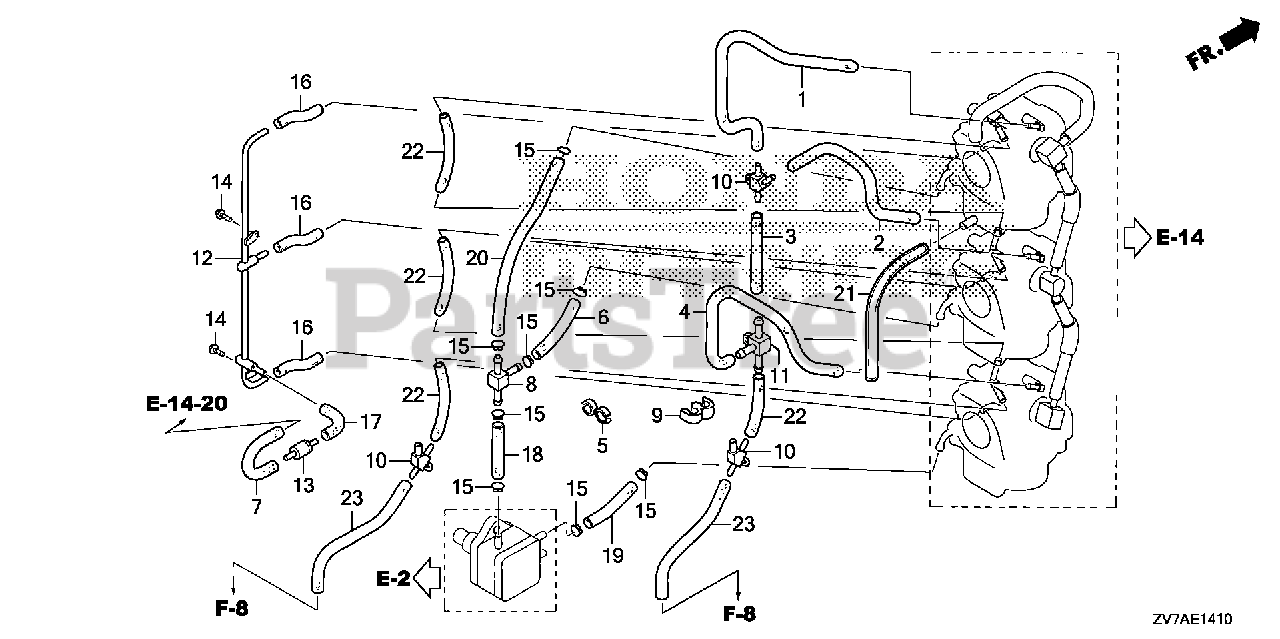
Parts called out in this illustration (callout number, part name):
1	TUBE, AIR VENT (A)
2	TUBE B, AIR VENT
3	TUBE C, AIR VENT
4	TUBE D, AIR VENT
5	CLAMP, FUEL TUBE (A)
6	TUBE C, FUEL
7	TUBE D, FUEL
8	PIPE, THREE WAY JOINT
9	CLAMP, TUBE (7.5X2)
10	JOINT, THREE WAY
11	JOINT, THREE WAY
12	PIPE, INSTALL
13	VALVE, DASHPOT CHECK
14	BOLT, FLANGE (5X10) (CT200)
15	CLIP, TUBE (B10)
16	BULK HOSE, FUEL (3.5X3000) (3.5X45)
17	BULK HOSE, FUEL (3.5X3000) (3.5X65)
18	TUBE, FUEL
19	TUBE, FUEL (5.3X55)
20	TUBE, FUEL (5.3X70)
21	BULK HOSE, VINYL (4.5X8X1000) (95003-09001-60M)
22	BULK HOSE, VACUUM (4.5X1000) (4.5X93)
23	BULK HOSE, VACUUM (4.5X1000) (4.5X110)
